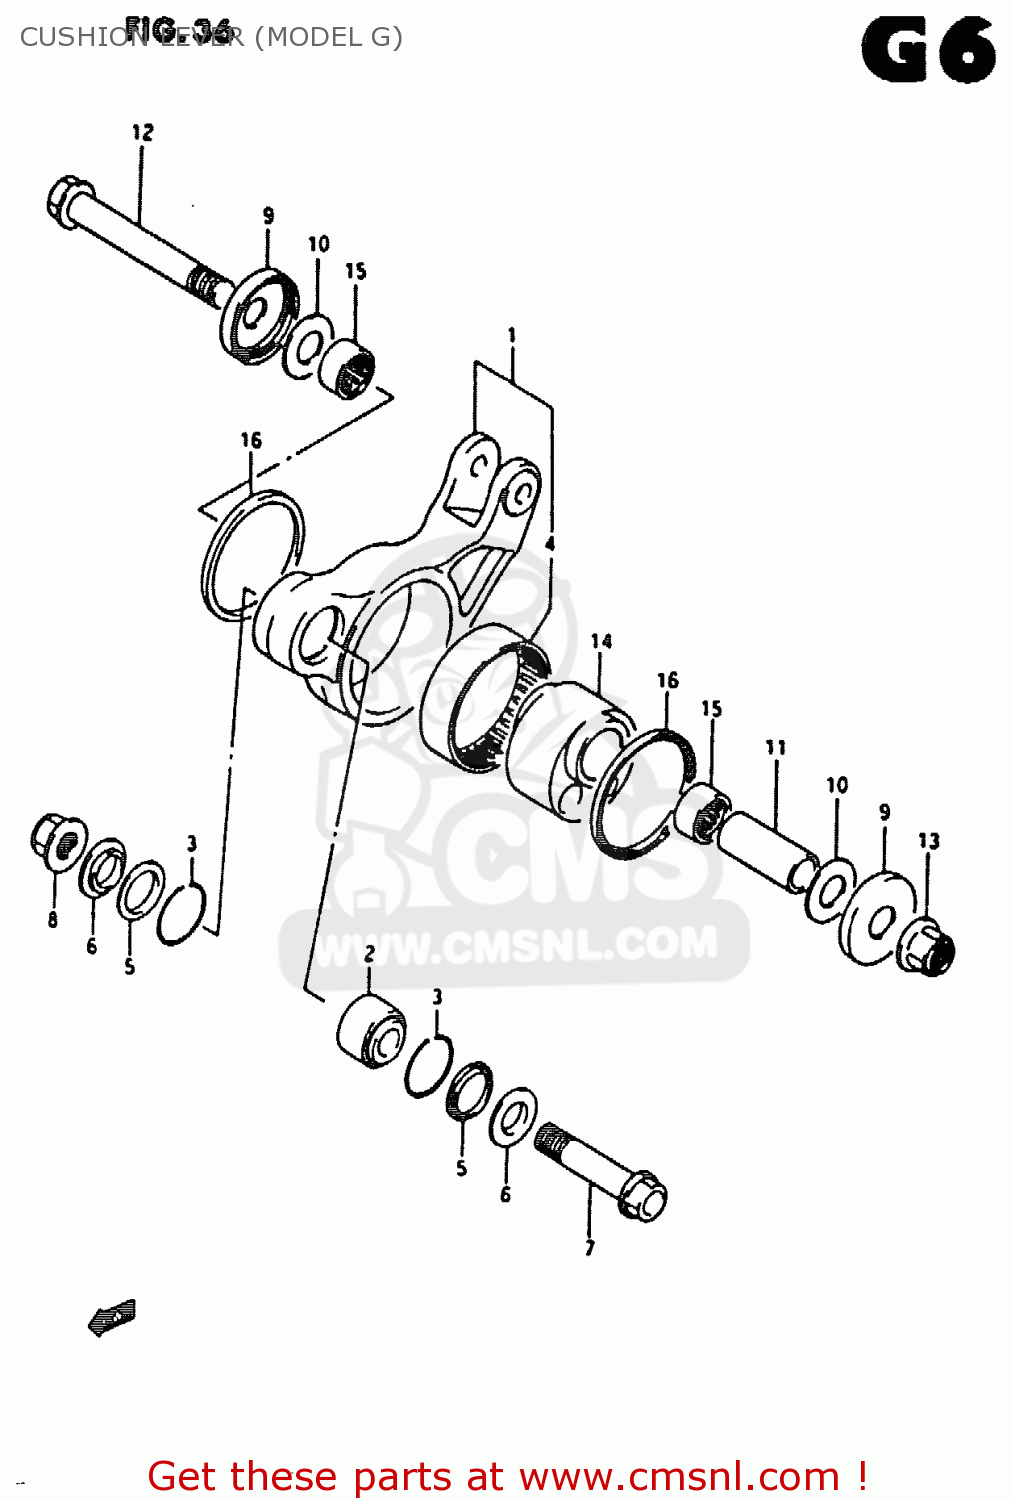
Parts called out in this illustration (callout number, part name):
1	LEVER SET,REAR CUSHION
2	SPHERICAL BEARING (14X2)
3	RING,BEARING STOPPER
4	BEARING(55X63X25)
5	SEAL,REAR CUSHION LEVER
6	SPACER,RR CUSHION LEVER FR
7	BOLT,RR CUSHION LEVER FR
8	NUT
9	DUST SEAL,RR C
10	WASHER
11	SPACER,REAR CUSHION LEVER
12	SHAFT,RR CUSHION LEVER
13	NUT
14	SPACER,REAR CUSHION ECCENTRIC
15	BEARING(20X27X20)
16	SEAL,RR CUSHION LEVER DUST
